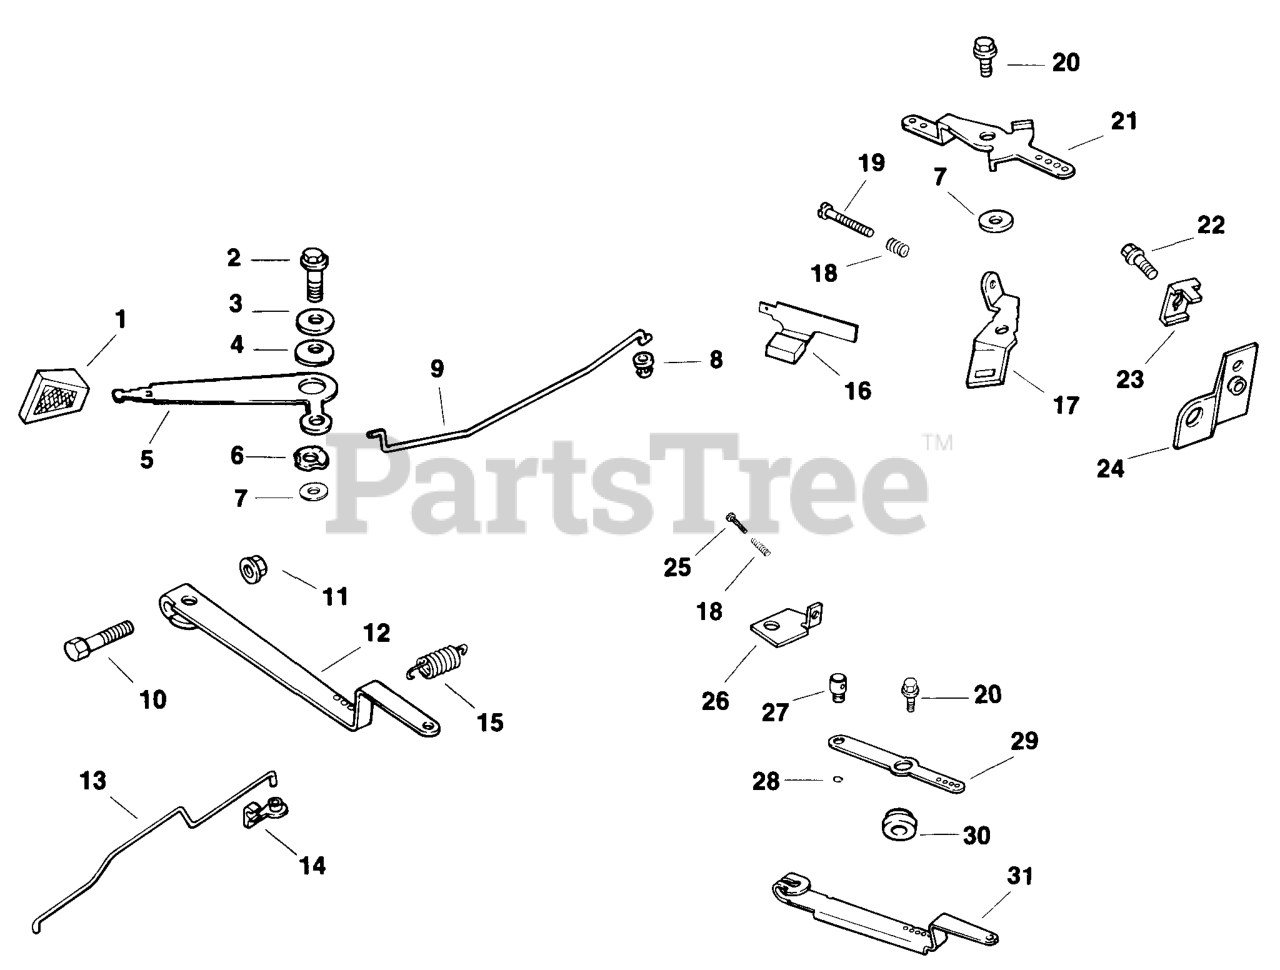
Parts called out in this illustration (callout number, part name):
10	USE SM-642025-S
11	Nut, governor output M6x1
13	LINKAGE-DISCONTINUED
14	BUSHING - USE 25 158 11
18	SPRING & KEEPER - (#DSC)
20	Screw, hex flange M6x1.0x20
25	SCREW, PHLLP PAN M4X0.7X50 - DISCONTINUED
29	LEVER, SPEED CONTROL
